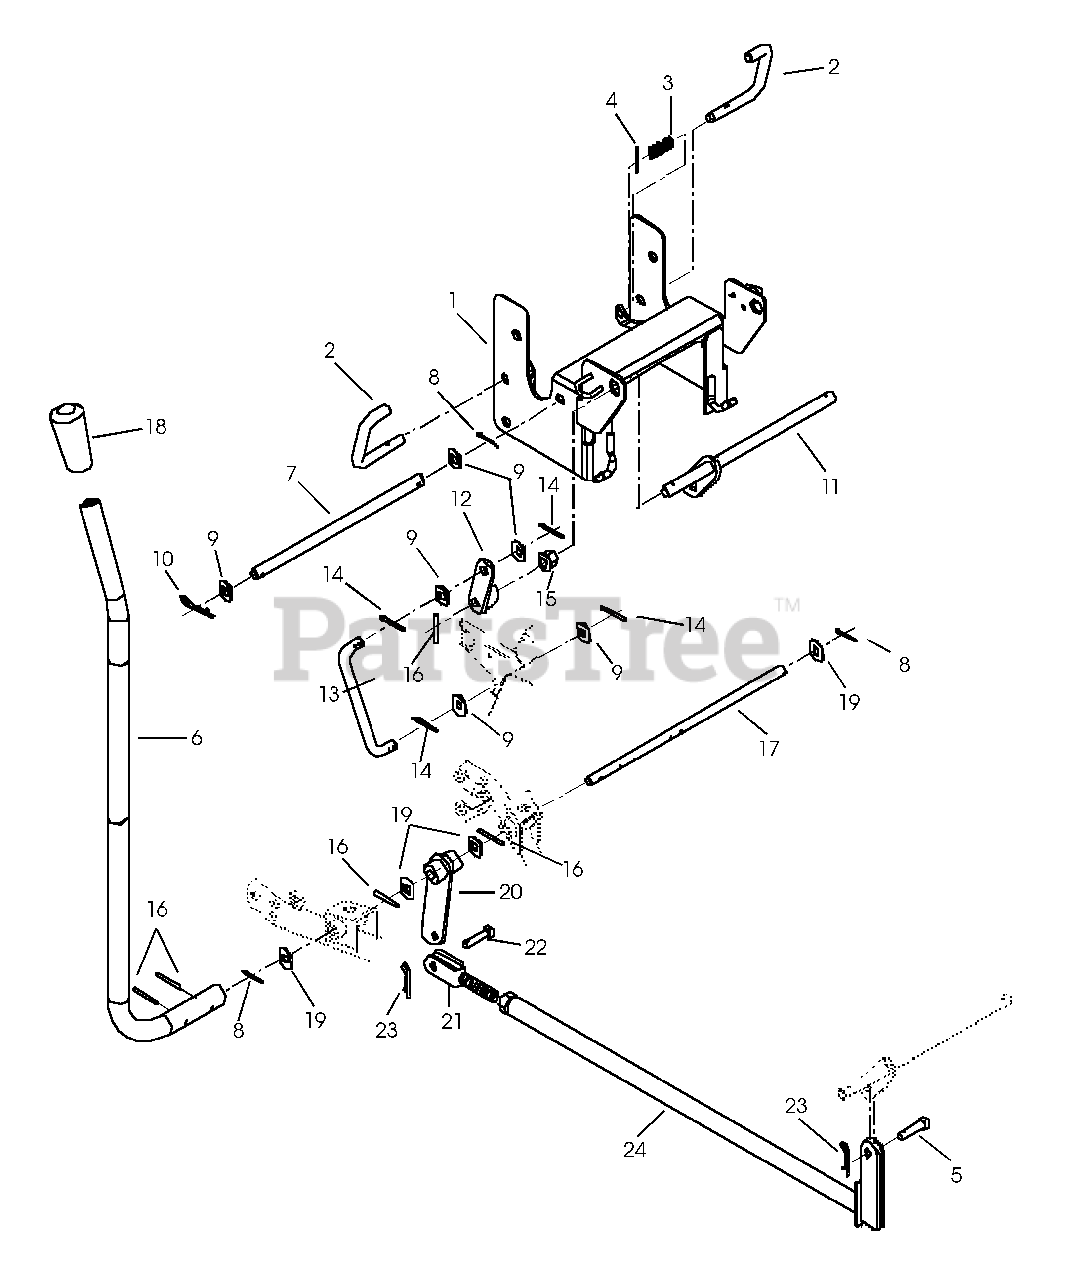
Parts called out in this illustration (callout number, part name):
1	Frame-Pivot
2	Pin-Latch
3	Spring-Compression .072 x .77 x 1.75
4	Pin-Roll .188 x 1.00
5	Clevis Pin .500 Diameter x 1.000
6	Lever
7	Rod-Pivot
8	Pin-Cotter .12 x 1.25
9	Washer-Flat-Steel .656 x 1.31 x .095
10	Pin-Hair Internal .17 x .68 x 3.50
11	Pivot Rod
12	Lever-Right Hand
13	Link
14	Pin-Cotter .12 x 1.0
15	Bushing-Flange .750 x .873 Hex x .53 x 1.18
16	Pin-Grove .250 x 1.50
17	Pivot Rod
18	Grip-Handle Bar
19	Washer-Flat-Steel .754 x 1.125 x .062
21	Clevis-Right Hand
22	Clevis Pin .491/.496 x 1.25
23	Pin-Hair Internal .14 x .43 x 2.75
24	Lift Tube
